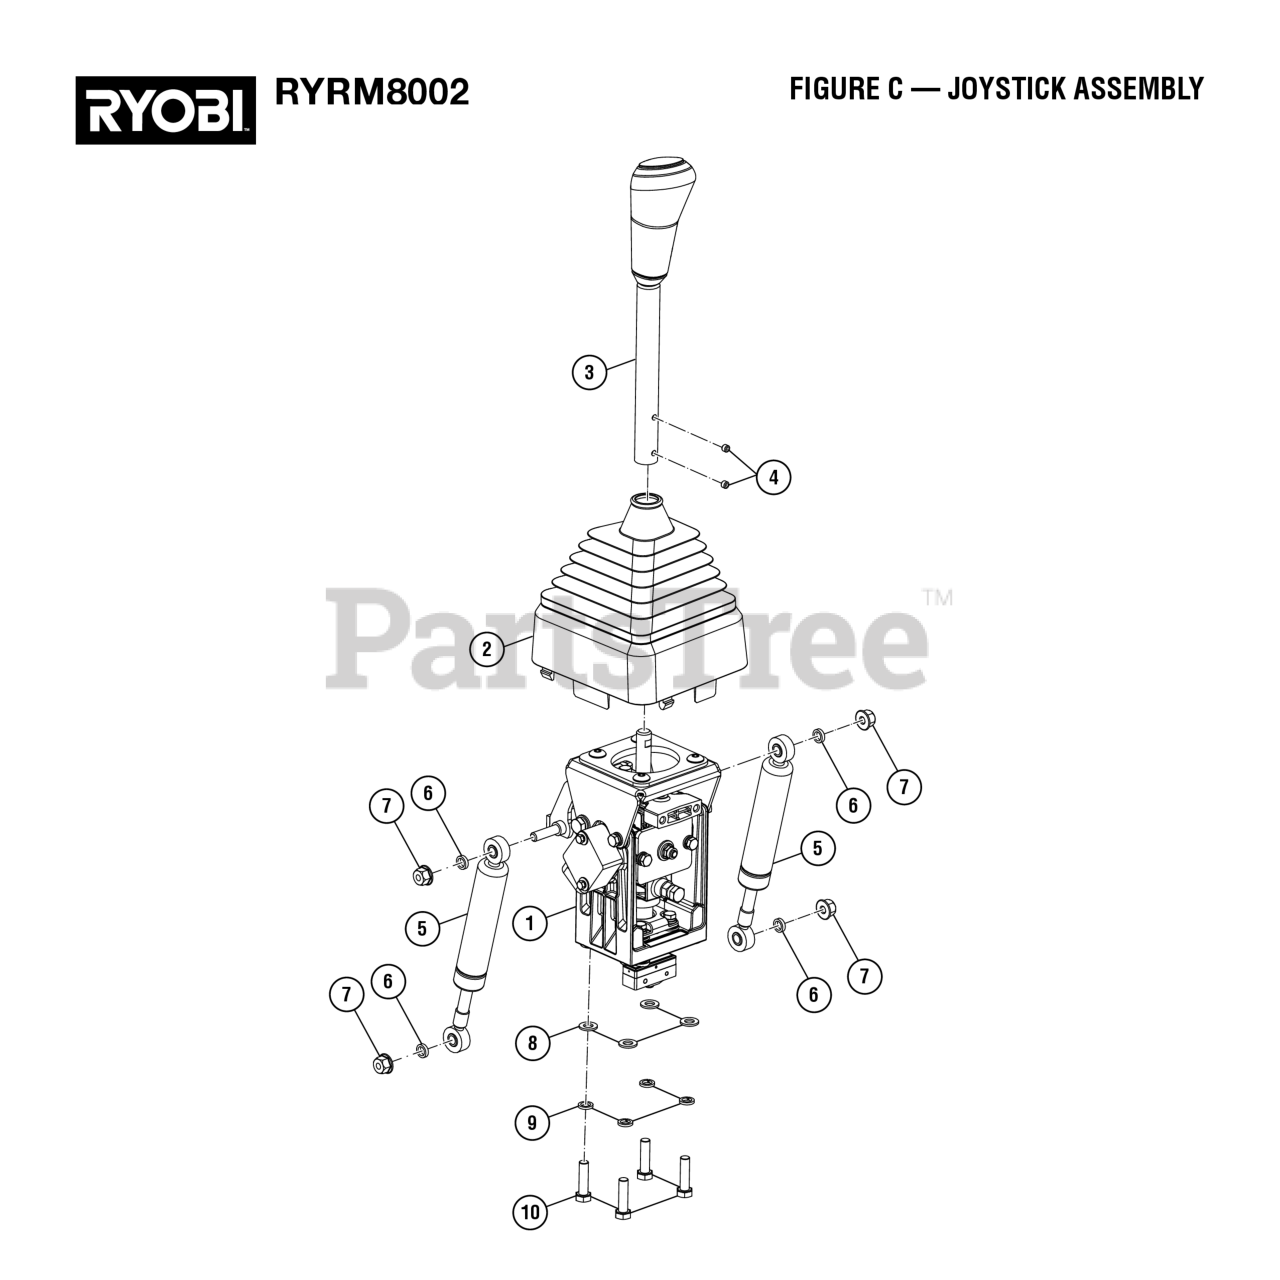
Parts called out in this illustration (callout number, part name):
1	Joystick Assembly
2	Joystick Bellow Assembly
3	Upper Joystick Handle
4	Set Screw (M6 x 8 mm)
5	Joystick Damper
6	Damper Bushing
7	Flange Nut (M8) (For Drive Motor Controller V)
8	Washer (OD16 x ID8.4 x 1.6t)
9	Lock Washer (OD9.8 x ID8.5 x 5t)
10	Screw (M8 x 30 mm, Hex Hd.)
